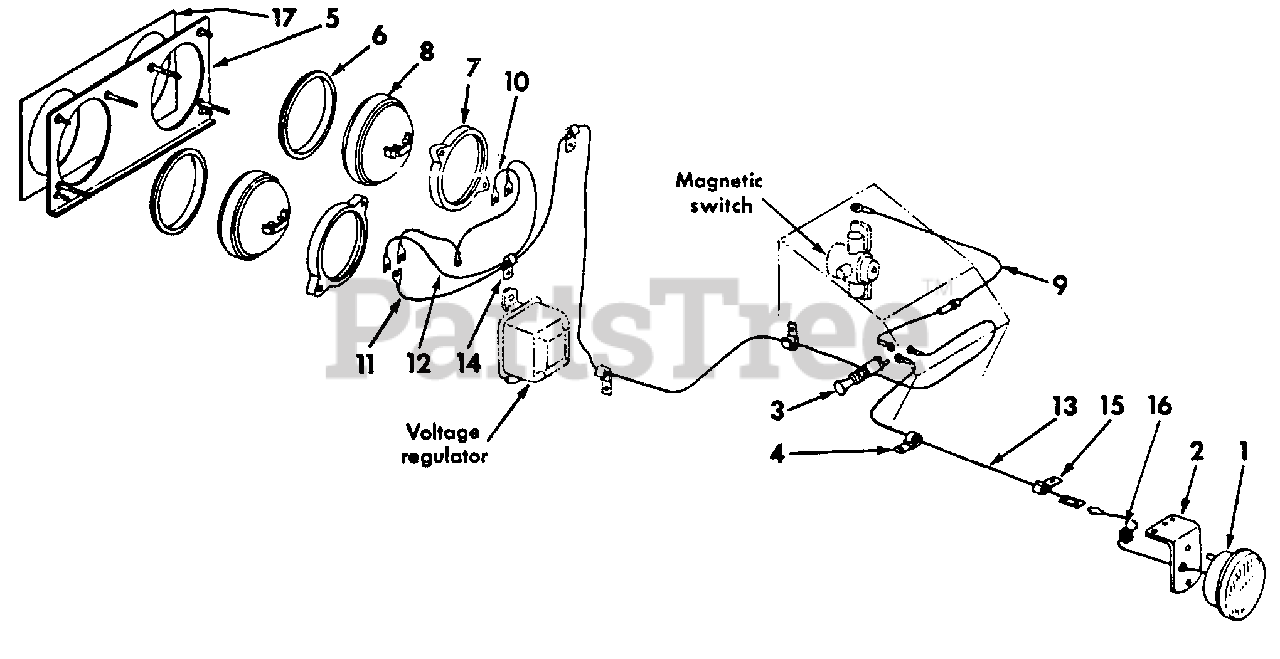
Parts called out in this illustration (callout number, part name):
1	Taillight Assy
2	Bracket, Taillight Mounting
3	Switch Assy, Lighting
4	Clip, Taillight Cable Snap On
5	Panel Assy, Headlight Mounting
6	Ring, Headlight Retaining
7	Ring, Headlight Clamp
8	Unit Assy, Sealed Beam Headlight
9	Cable Assy, Lighting Switch to Magnetic Switch
10	Cable Assy, Headlight to Ground
11	Cable Assy, Lighting Switch to LH Headlight
12	Cable Assy, RH Headlight to LH Headlight
13	Cable Assy, Lighting Switch to Taillight
14	Clip, Headlight Cable
15	Clip, Lighting Switch to Taillight Cable
16	Grommet, Taillight Cable
17	Product Graphics, Headlight Panel
